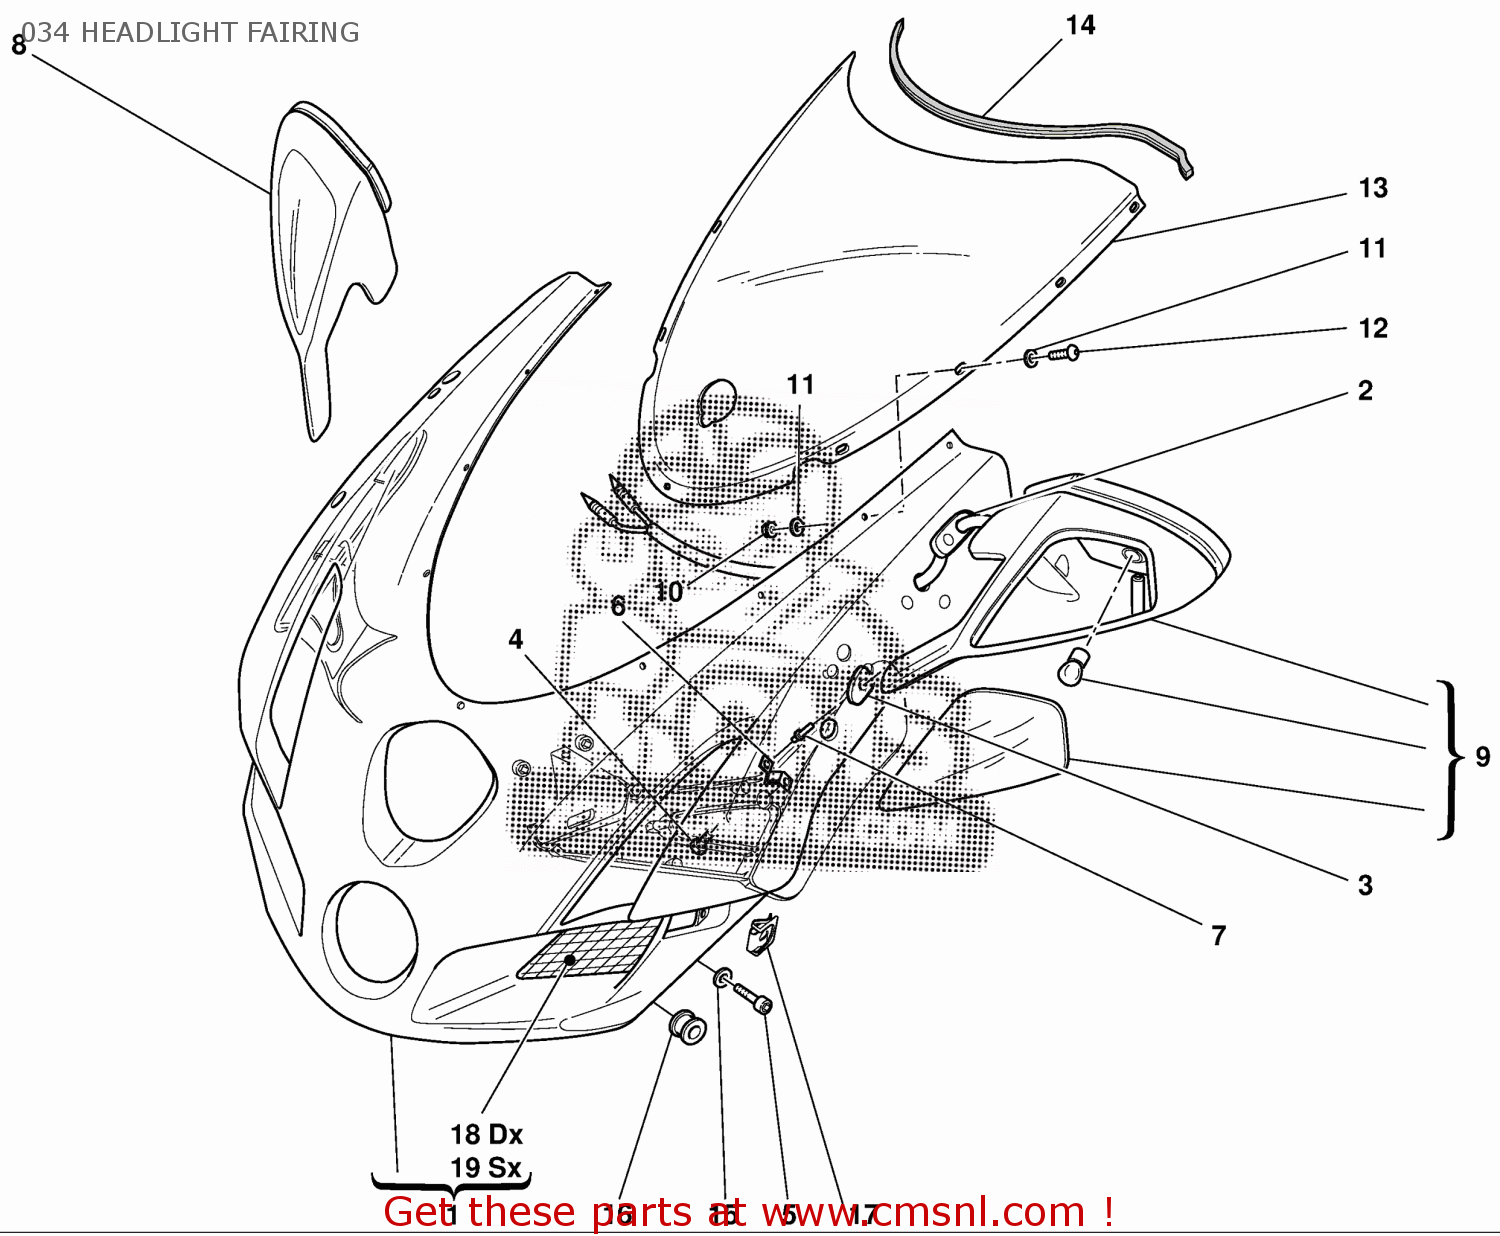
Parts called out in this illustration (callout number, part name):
1	COWLING UNPAINTED
2	GASKET, MIRROR LH
3	GASKET, MIRROR RH
4	SCREW
5	SCREW
6	SPRING
7	SHEAR RIVET 3X8
8	MIRROR, RIGHT RED
9	MIRROR, LEFT RED
10	NUT, SPRING
11	WASHER, NYLON 4X8X0.5
12	SCREW, SPECIAL
13	WINDSHIELD
14	WINDSCREEN PROTECTION RUBBER
15	SPRING WASHER 8.1X14X1
16	VIBRATION DAMPER PAD
17	QUICK FASTENING
18	RIGHT COVER
19	PROTECTION, LEFT
